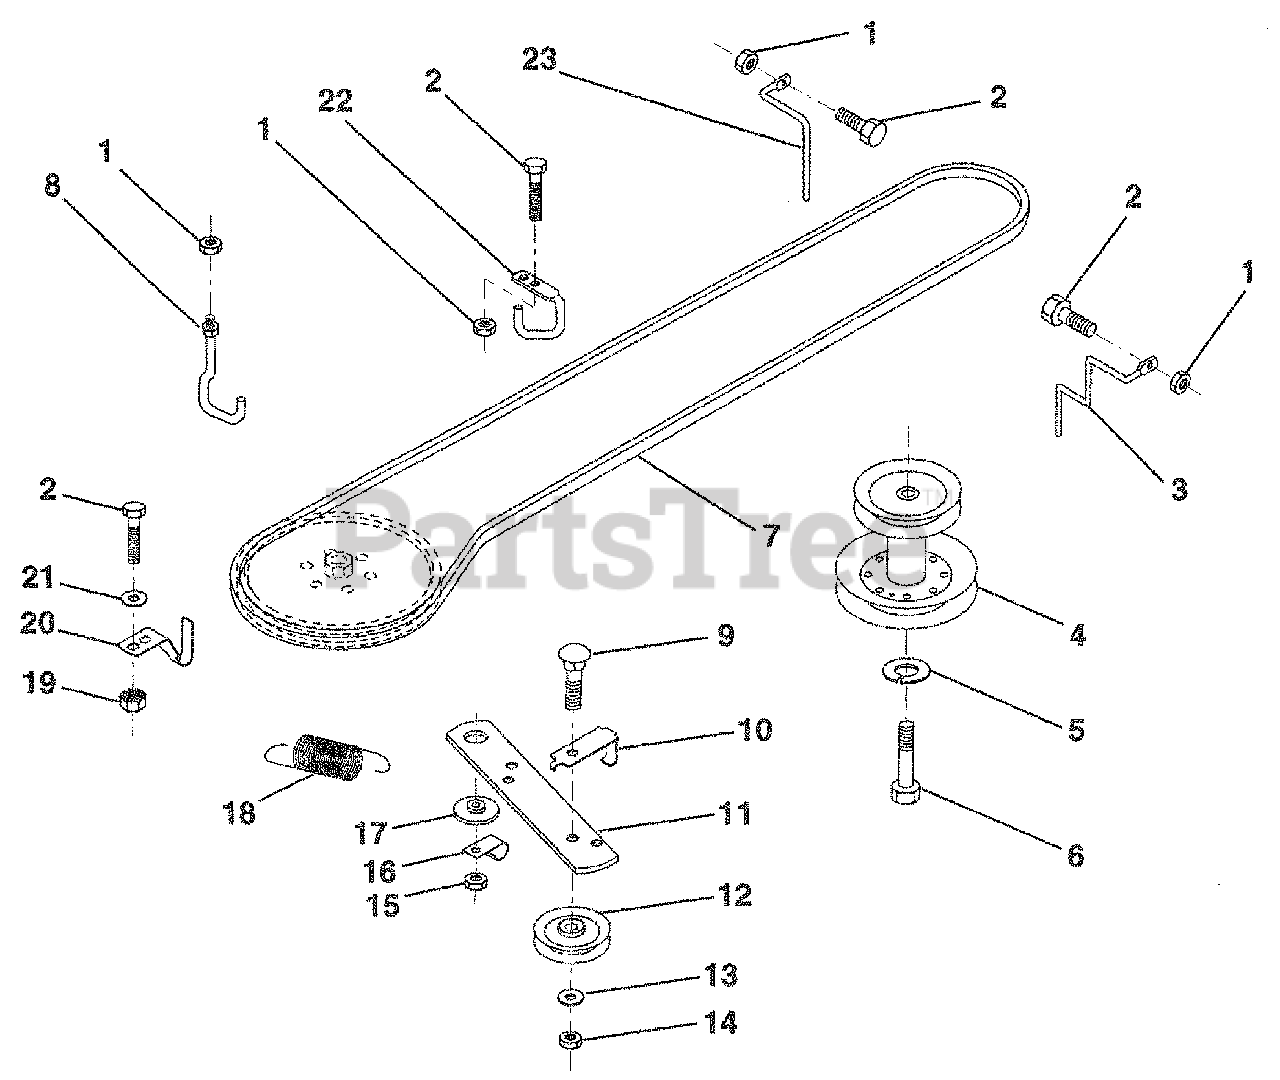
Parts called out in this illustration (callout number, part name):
1	Nut, Crownlock 5/16-18
2	Bolt, Hex Hd 5/16 -18 UNC x 3/4
3	Keeper.Mower Drive, R. H.
4	Pulley, Engine
5	Washer, Lock 7/16
6	Bolt, Fin. Hex 7/16-20
7	Traction, V-Belt Drive
8	Keeper, T/A Ground Drive Belt
9	Bolt, Carr. 3/8 -16 UNC x 1-1/2
10	Keeper, Belt Ground Drive idler
11	Arm, Ground Drive Clutch
12	idler, Flat
13	Washer 13/32 x 13/16 x 16 Ga.
14	Nut, Centerlock 3/8 -16 UNC
15	Nut, Crowniock 3/8 -16 UNC
16	Clip, insulated
17	Spacer, Retainer
18	Spring Extension
19	Nut, Keps 5/16-18 UNC
20	Keeper, T/A Ground Drive Belt
21	Washer 11/32 x 5/8 x 16 Ga.
22	Keeper, Frame Ground Drive Belt
23	Keeper, Mower Drive, L. H.
